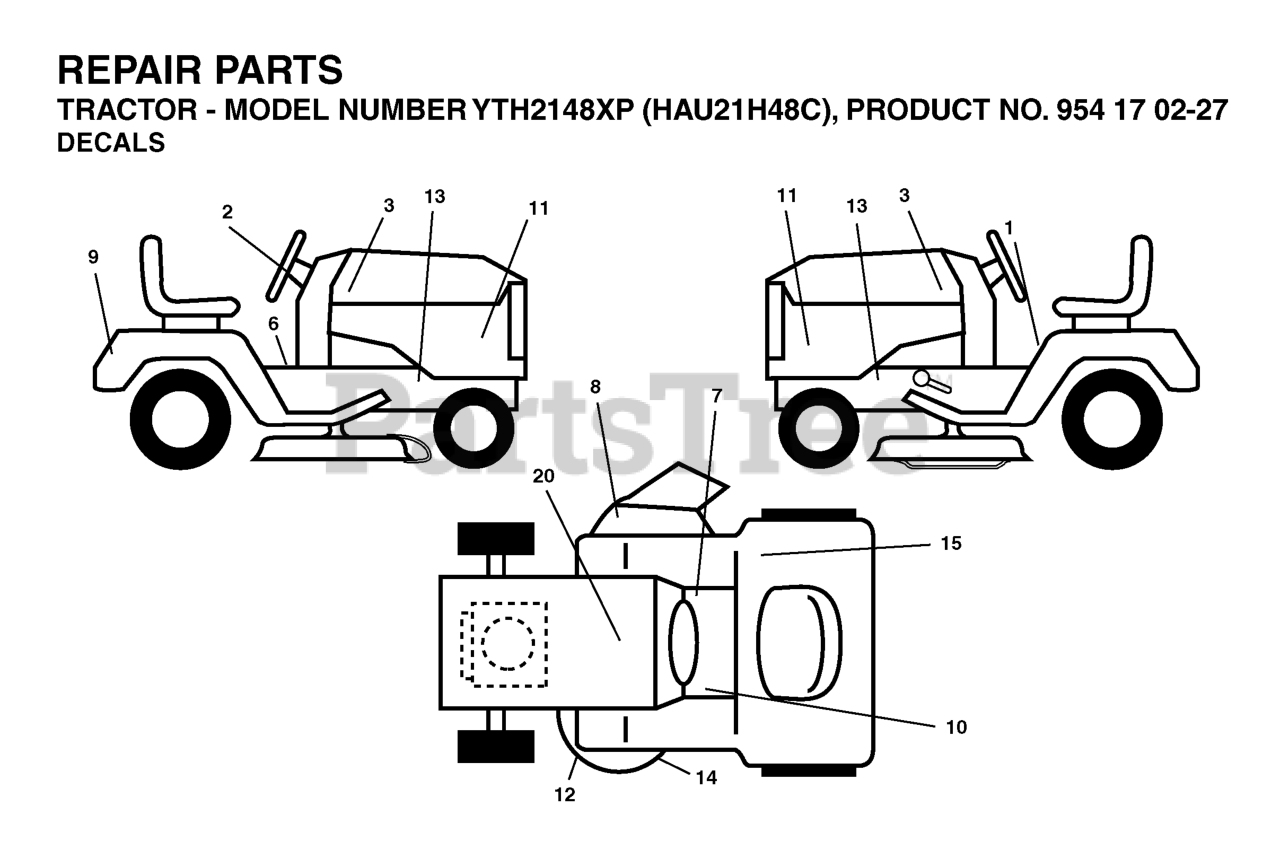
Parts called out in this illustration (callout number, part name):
1	DECAL READ OWNER'S MAN SYMS
2	DECAL.STEERING.HUSQ.BLUE
3	DECAL.HOOD.HUSQVARNA.INTERNATI
6	DECAL
7	DECAL PARK BRAKE
8	DECAL.INTERNATIONL.CUTFINGER
10	DECAL
12	DECAL CLUTCH/BRAKE
14	DECAL V-BELT SCHEMATIC
15	DECAL
20	DECAL BTRY SYMBOLS
